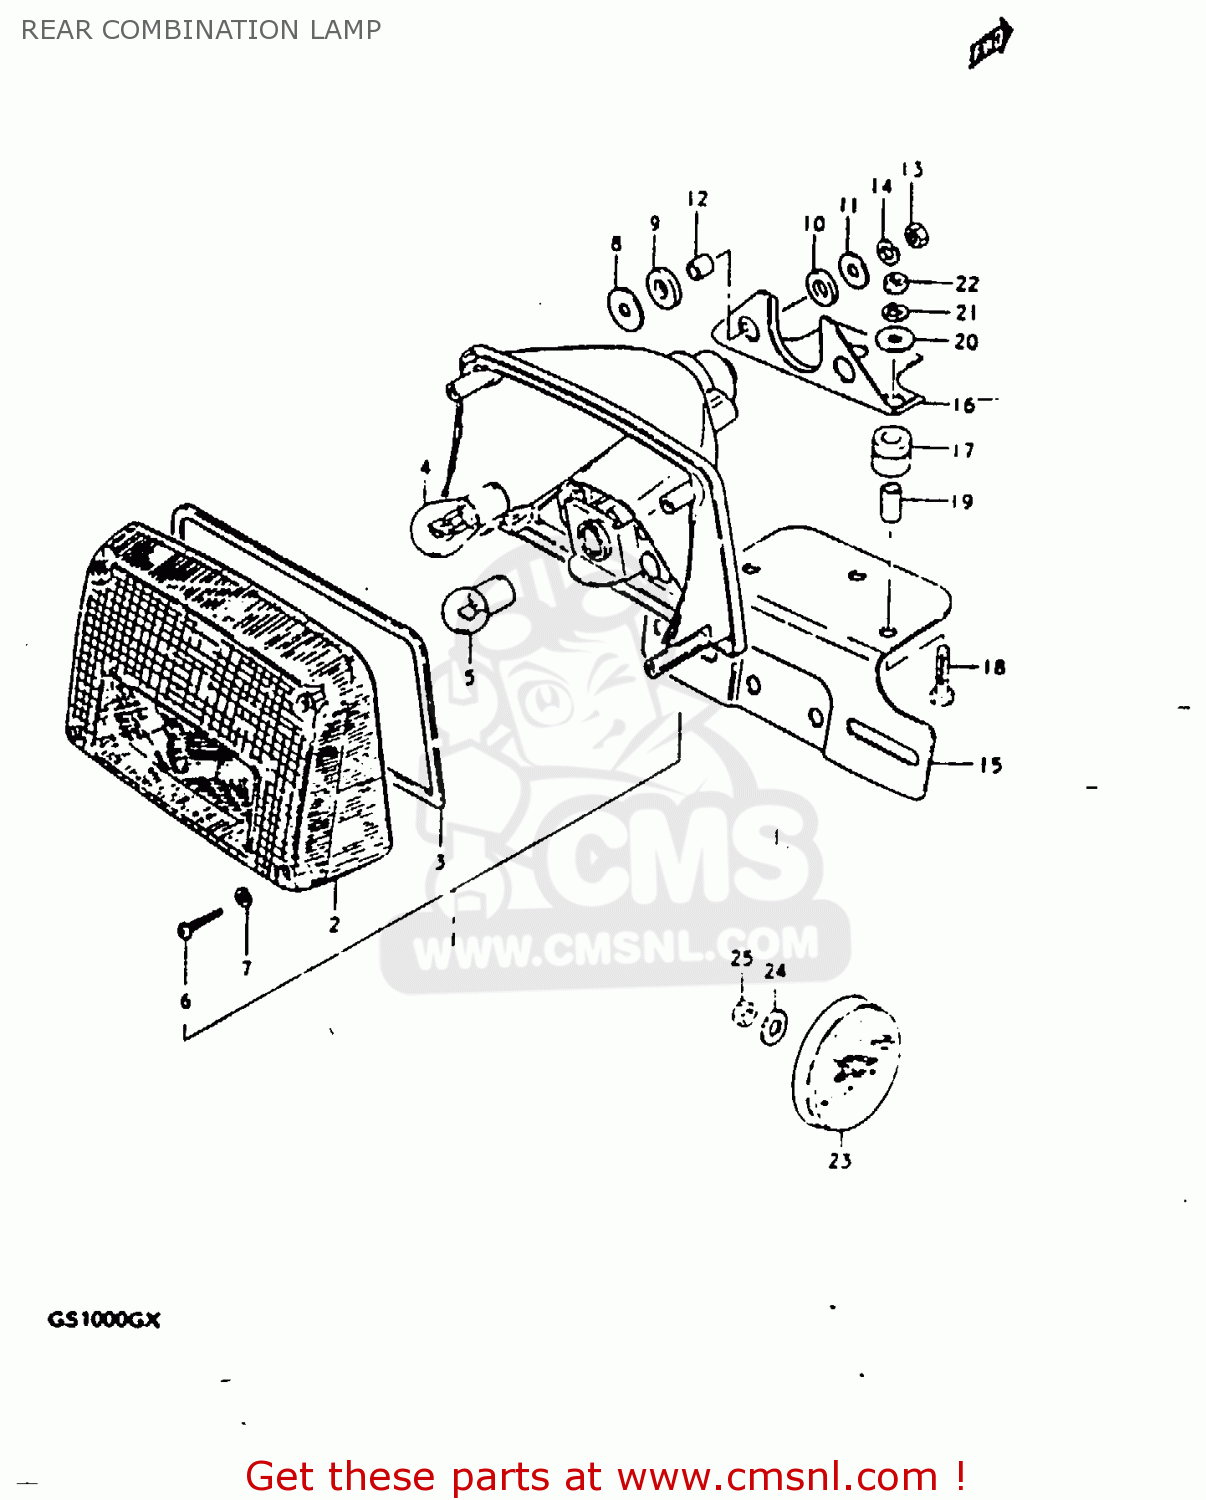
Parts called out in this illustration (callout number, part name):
1	LAMP ASSEMBLY,REAR COMBINATION
2	LENS
3	GASKET (NAS)
4	BULB(12V23W)
5	BULB
6	BOLT
7	GASKET (NAS)
8	WASHER
9	CUSHION
10	CUSHION
11	WASHER(6,5X22X1.6)
12	SPACER(6.1X9X7.5)
13	NUT
14	LOCK WASHER
15	BRACKET, LICENCE PLATE
16	BRACKET,LICENSE PLATE
17	CUSHION, BRACKET
18	BOLT
19	SPACER (6.4X9X15.5)
20	WASHER
21	LOCK WASHER
22	NUT
23	REFLEX REFLECTOR,RR
24	WASHER
25	NUT
